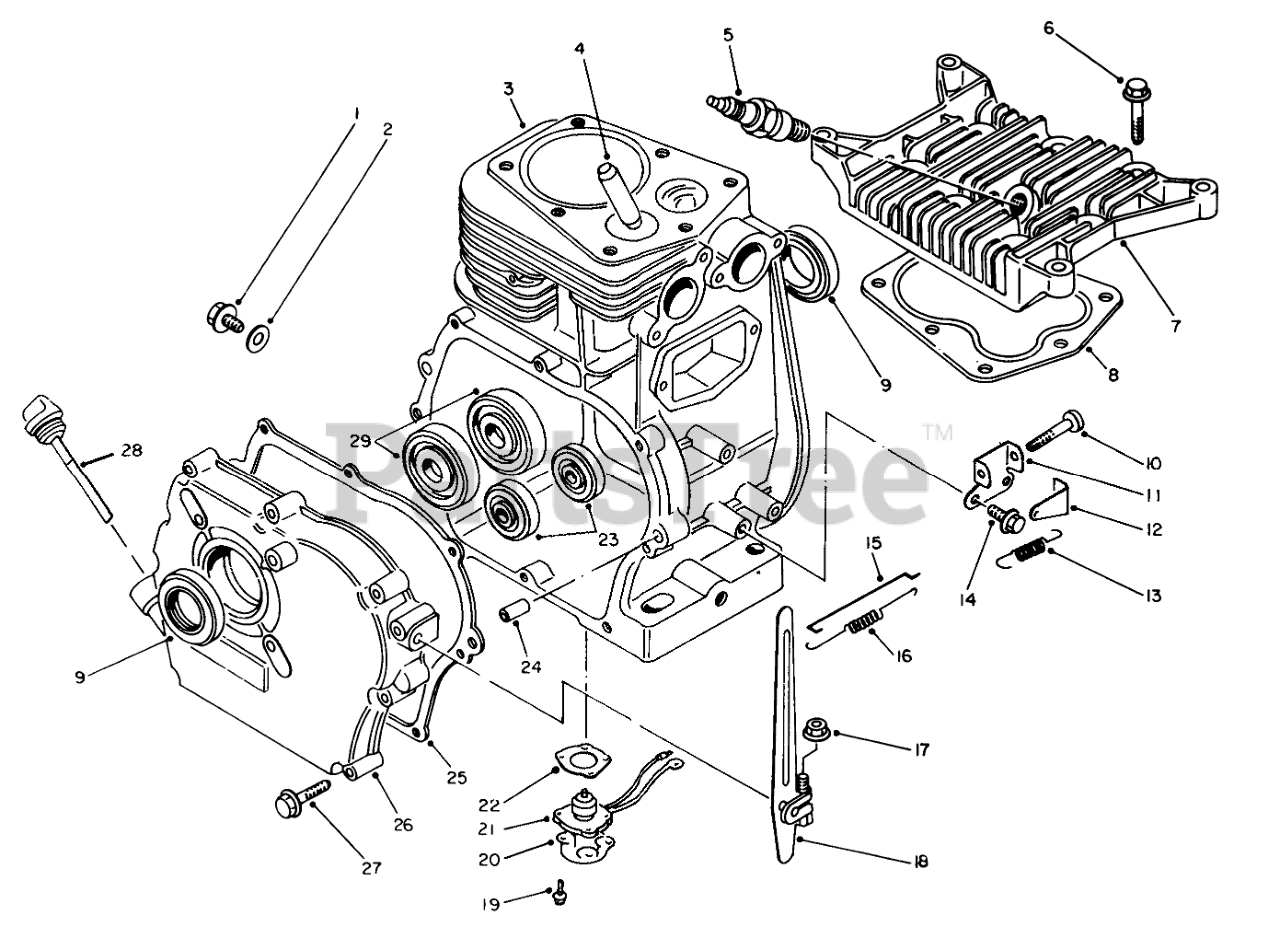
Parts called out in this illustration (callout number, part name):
1	Drain Plug
2	GASKET
3	Cylinder
4	VALVE GUIDE
5	SPARK PLUG
7	Cylinder Head
8	GASKET
9	OIL SEAL
11	Bracket
13	SPRING
15	Rod
16	SPRING
18	Control Lever
20	Plate
21	SENSOR
22	GASKET
23	Bearing
25	Gasket
26	Cover
28	Gasket
29	Screw
